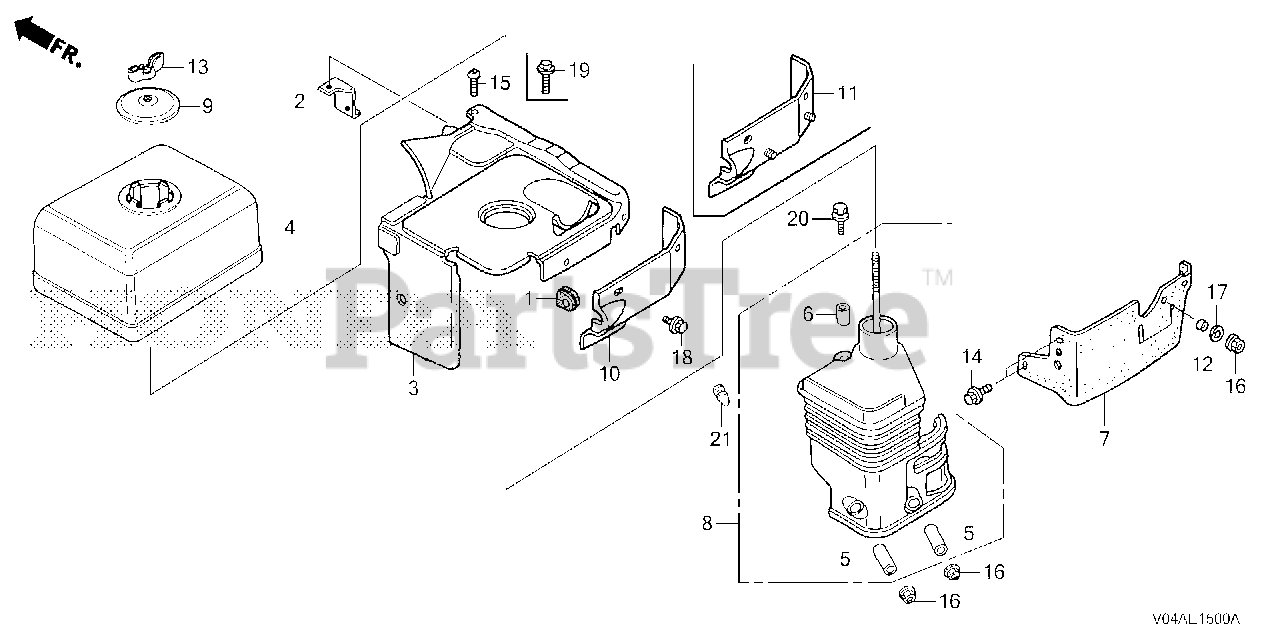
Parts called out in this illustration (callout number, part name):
1	GROMMET, OIL PIPE HOLDER
2	STAY, ENGINE CONTROL COVER
3	COVER, CONTROL
4	COVER, AIR CLEANER (SEMI-DRY)
5	COLLAR, AIR CLEANER Use from Engine SN 1786085.
6	COLLAR B, AIR CLEANER
8	ELBOW, AIR CLEANER
9	CAP, AIR CLEANER
10	COVER, AIR IN.
13	WINGNUT, TOOL BOX SETTING
15	SCREW, PAN (6X8) (SOURCE: VINTAGE PARTS INC.)
16	NUT, FLANGE (6MM)
18	BOLT, FLANGE (6X8)
20	BOLT, FLANGE (6X20)
21	PLUG, CONE TYPE
